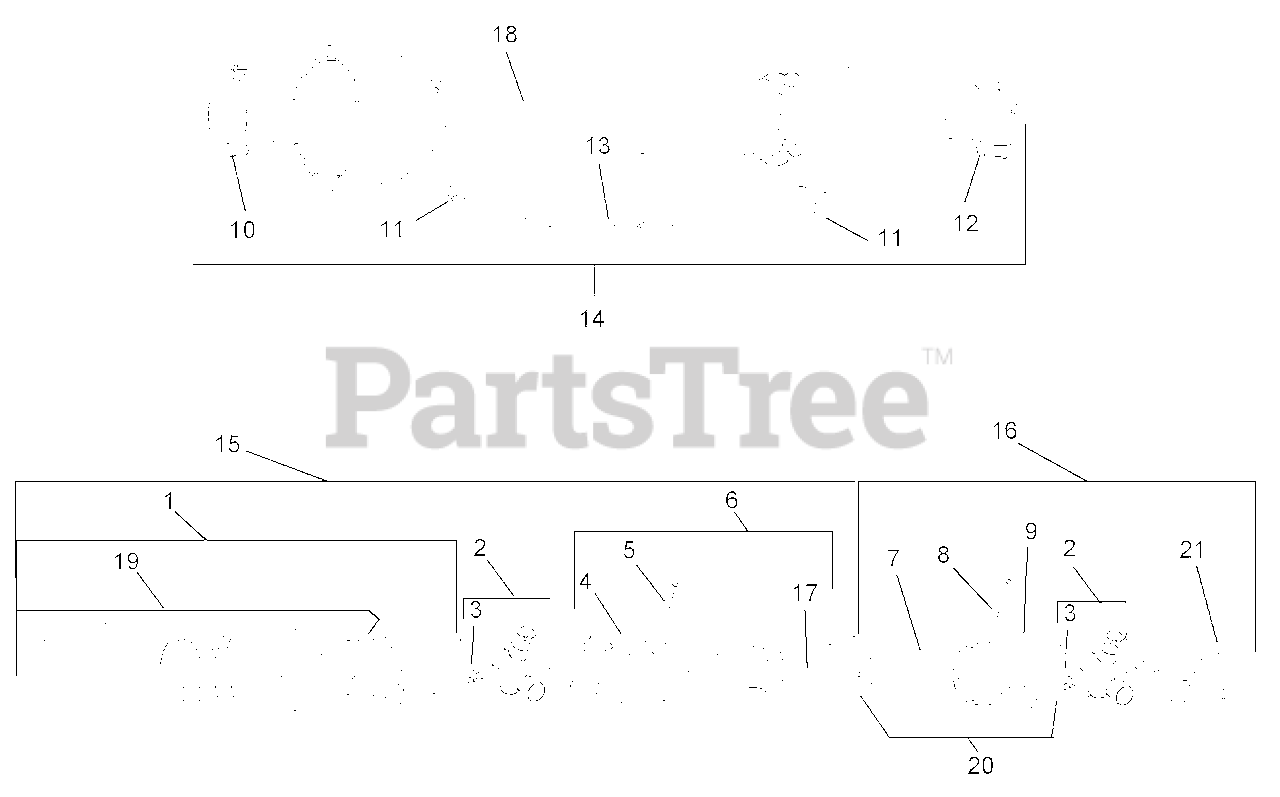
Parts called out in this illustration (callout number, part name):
1	Yoke, Complete Collar
2	Kit, Cross and Bearing
3	Fitting, Grease 45 Degree 8 mm x 1 mm x .88
4	Yoke, Outer Tube
5	Roll Pin, Inner Yoke
6	Tube Assembly (includes items 4, 5 &17)
7	Tube, Inner
8	Roll Pin, Inner Yoke
9	Yoke, Inner Tube
10	Guard, Outer Collar Retaining
11	Fastener, Shield
12	Guard, Inner Collar Retaining
13	Chain, Safety
14	Shield, Complete With Instructions
15	Shaft, Female Half With Shields
16	Shaft, Male Half With Shields
17	Decal, Danger
18	Decal, Danger Driveline
19	Kit, Ball Collar 1.38
20	Male Tube & Yoke w/Roll Pin
21	Push Pin Yoke Assembly
